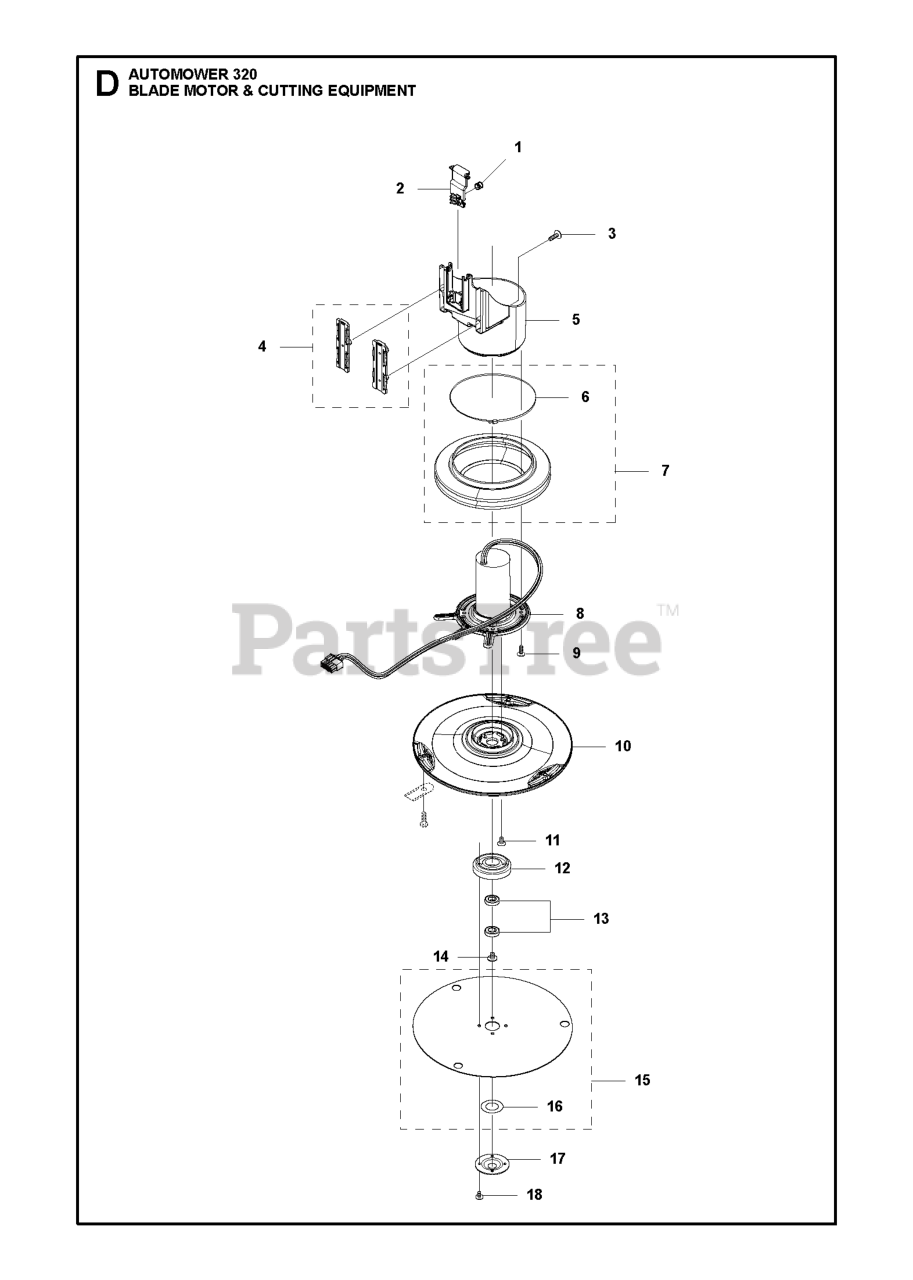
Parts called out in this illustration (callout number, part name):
1	SPRING LINK
2	LINK MOTOR HOUSING
3	SCREW 14MM
4	BEARING KIT
5	HOUSING CUTTING MOTOR
8	MOTOR ASSY CUTTING MOTOR
9	SCREW 14MM
11	SCREW
13	BALL BEARING BALL BEARING 535
13	BALL BEARING 2 RS,TIGHT CLEAR
17	COVER SKID PLATE
18	SCREW SILVER 10MM
